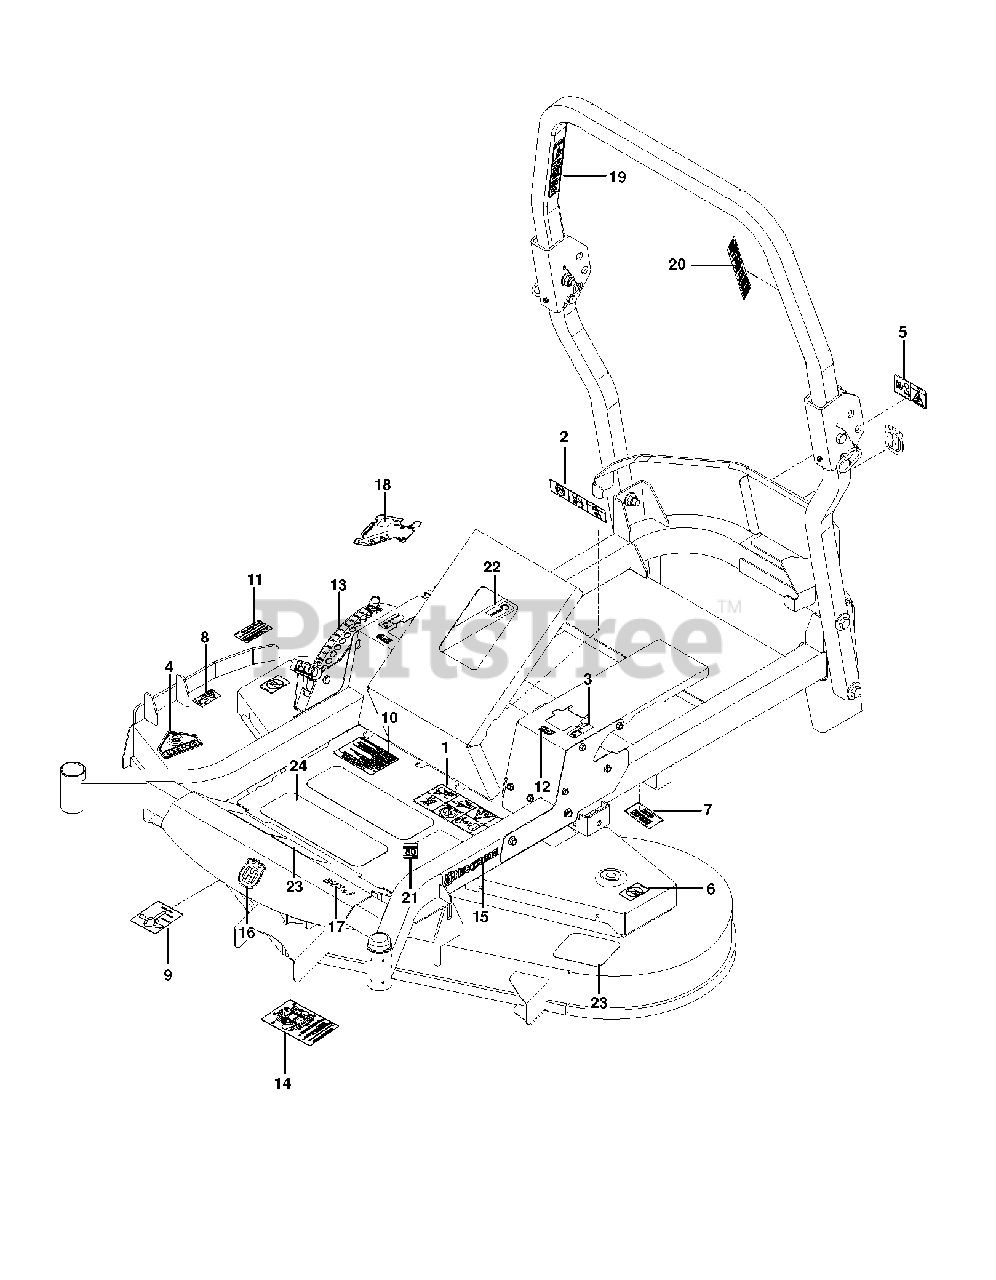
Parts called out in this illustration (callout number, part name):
1	DECAL, WARNING
2	EURO DECAL-BATTERY WARNIN6
3	DECAL, MOTION CONTROL
4	DECAL, CPSC
5	DECAL, BELT DRIVE
6	DECAL, NO STEP
7	HG_DECAL, ZT-3400
8	DECAL, EURO SEVERING
9	DECAL, BELT ROUTING
10	DECAL, WARNING
11	DECAL, CAUTION
12	DECAL, F.S.T.
13	DECAL, HEIGHT ADJUST
14	DECAL, SERVICE
15	RP.DECAL.BADGE.170MM.TEXTLOGO
16	DECAL.AUGER.HUSQ.CROWN.SNOW
17	DECAL.ZTR.MZT52.HUSQVARNA
18	DECAL, CONSOLE HUS
19	DECAL, ROPS, WARNING
20	DECAL ROPS
21	DECAL 80 DBA
22	DECAL, ECM, AUSTRALIA
24	ANTI-SKID PAD
